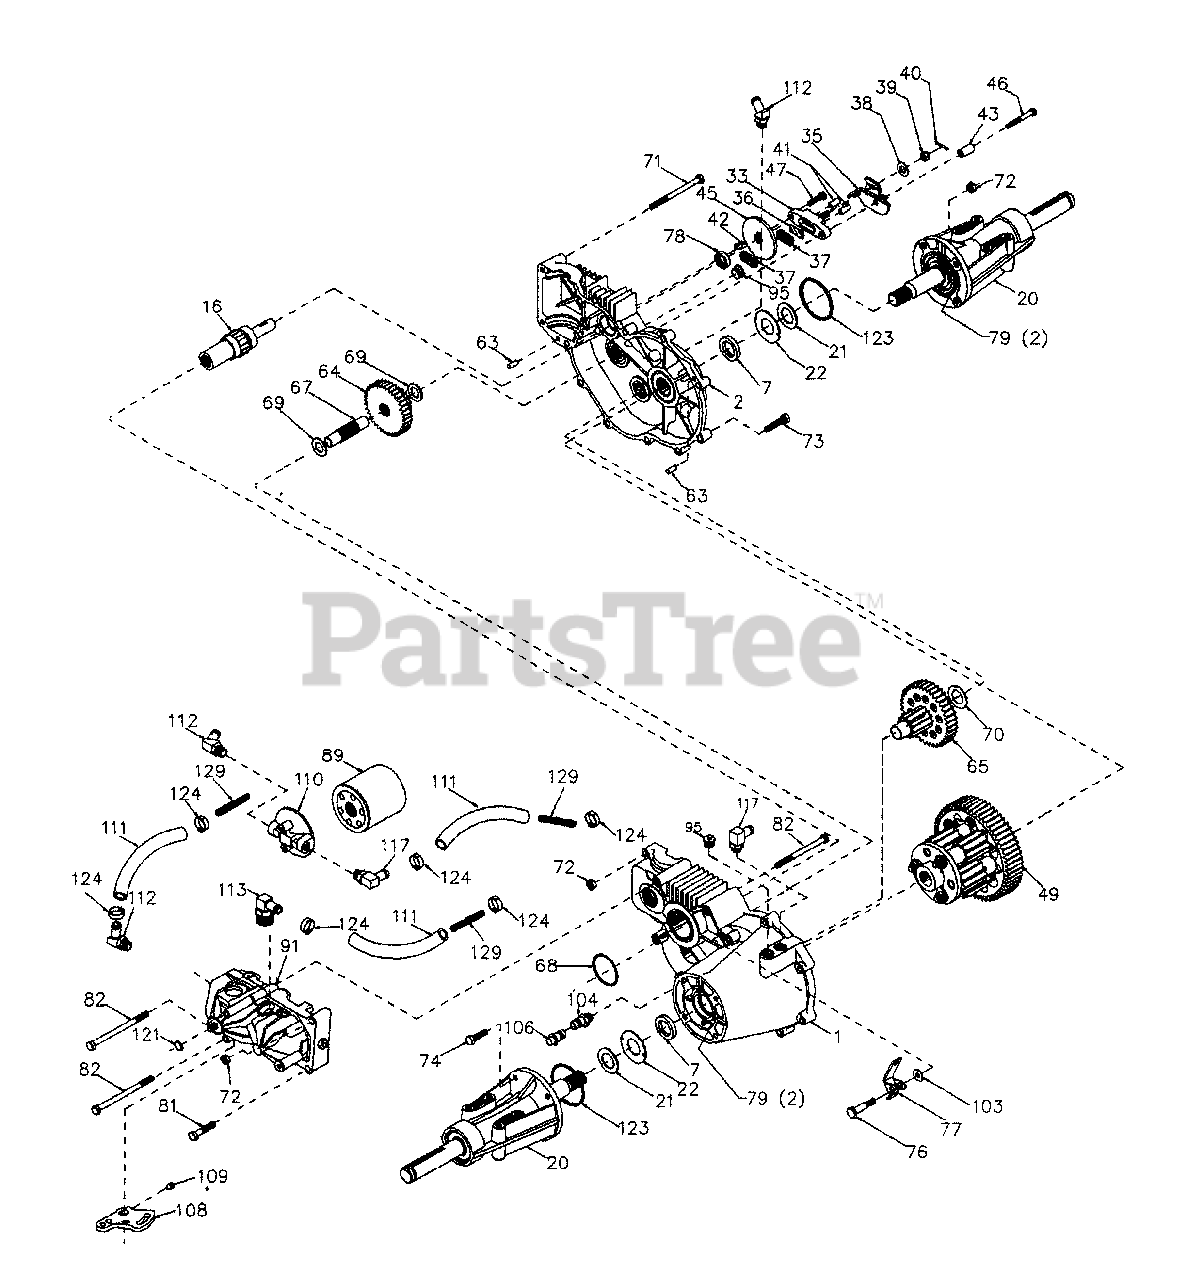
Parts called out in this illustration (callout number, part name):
1	Assembly, Housing, LH
2	Assembly, Housing, RH
7	Oil Seal .984 x 1.5 x .25
16	Brake Shaft Assembly
20	Axle Mounting Horn Assembly
21	Washer 1.0 x 1.63 x .OS
22	Washer 1.0 x 2.06 x .09
33	Brake Yoke Assembly
36	Puck Plate
37	Brake Puck
38	Washer 7/8 O.D. x 7/16 x .060
39	Nut, Castle 5/16-24
40	Cotter Pin
41	Brake Actuating Pin
42	Hi Pro Key
45	Brake Disc
46	Bolt 1 /4-20 x 1-1 /2
47	Bolt 1/4-20 x 1
49	Differential Assembly
64	Reduction Gear, 14 Teeth to 38 Teeth
65	Final -Drive Pinion Assembly
69	Washer 5/8 X 1-5/32
70	Washer 7/8 X 1-1/2
71	Bolt, Hex 5/16-18 x 3.5
72	Locknut, Hex 5/16-18
73	Bolt, Hex 5/16-18 x 1-1/2
74	Hex Cap Screw 5/16-18 x 1
76	Shoulder Bolt
77	Freewheel Actuating Arm
78	Oil Seal .625 x 1.0 x .25
79	Grease (10 oz. Tube)
81	Bolt, Hex 5/16-18 x 1-3/4
82	Bolt 5/16-18 x 4-1/2
89	Filter, Spin On
91	Pump, BDU-10L-122
95	Plug, Straight Thread
104	Vent Cap Assembly
106	Fitting O-Ring Assembly
108	Control Arm
110	Filter Head
112	Fitting, 1/2" Beaded 900 7/8 SAE
113	Fitting, 1/2" Beaded 600 9/16
117	Fitting, 1/2" Beaded 900 9/16
124	Pinch Clamp
129	Spring, Long
